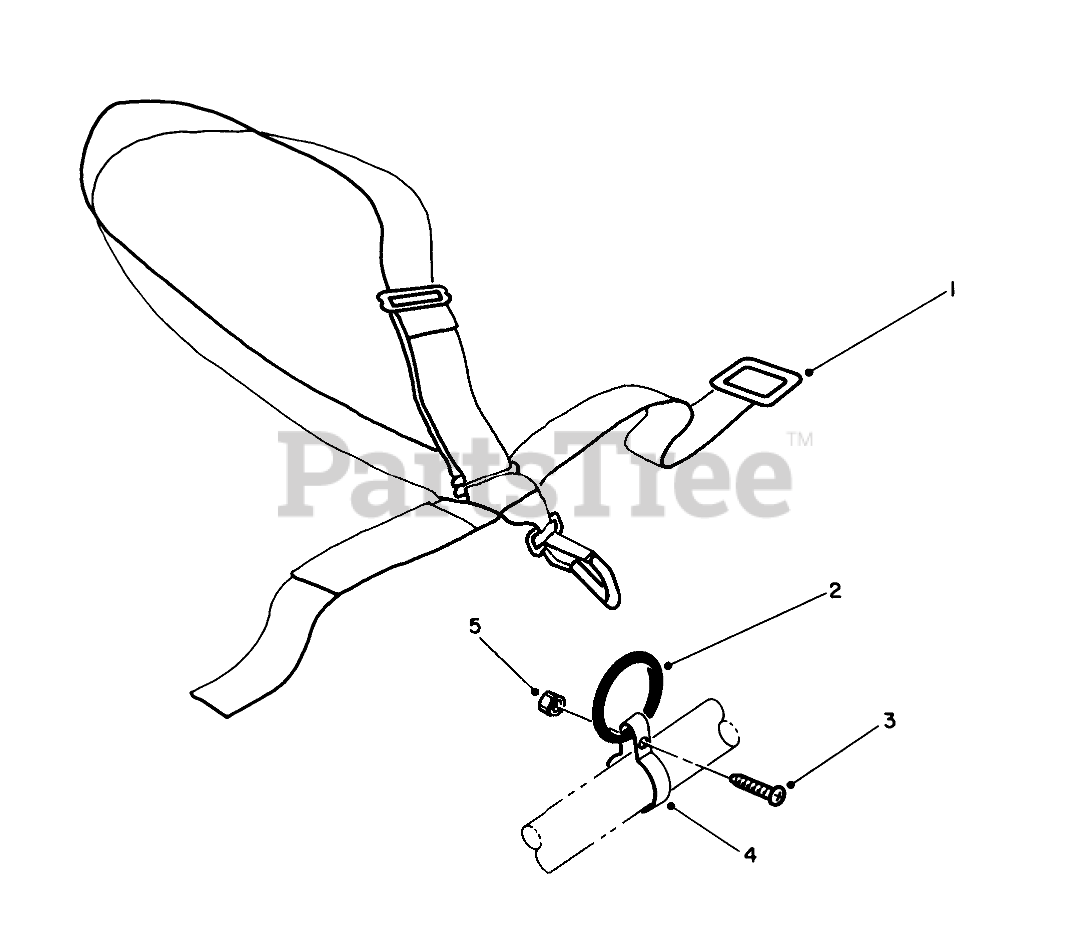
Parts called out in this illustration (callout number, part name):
1	Deluxe Harness
2	Ring
3	Clamp
5	Nut
